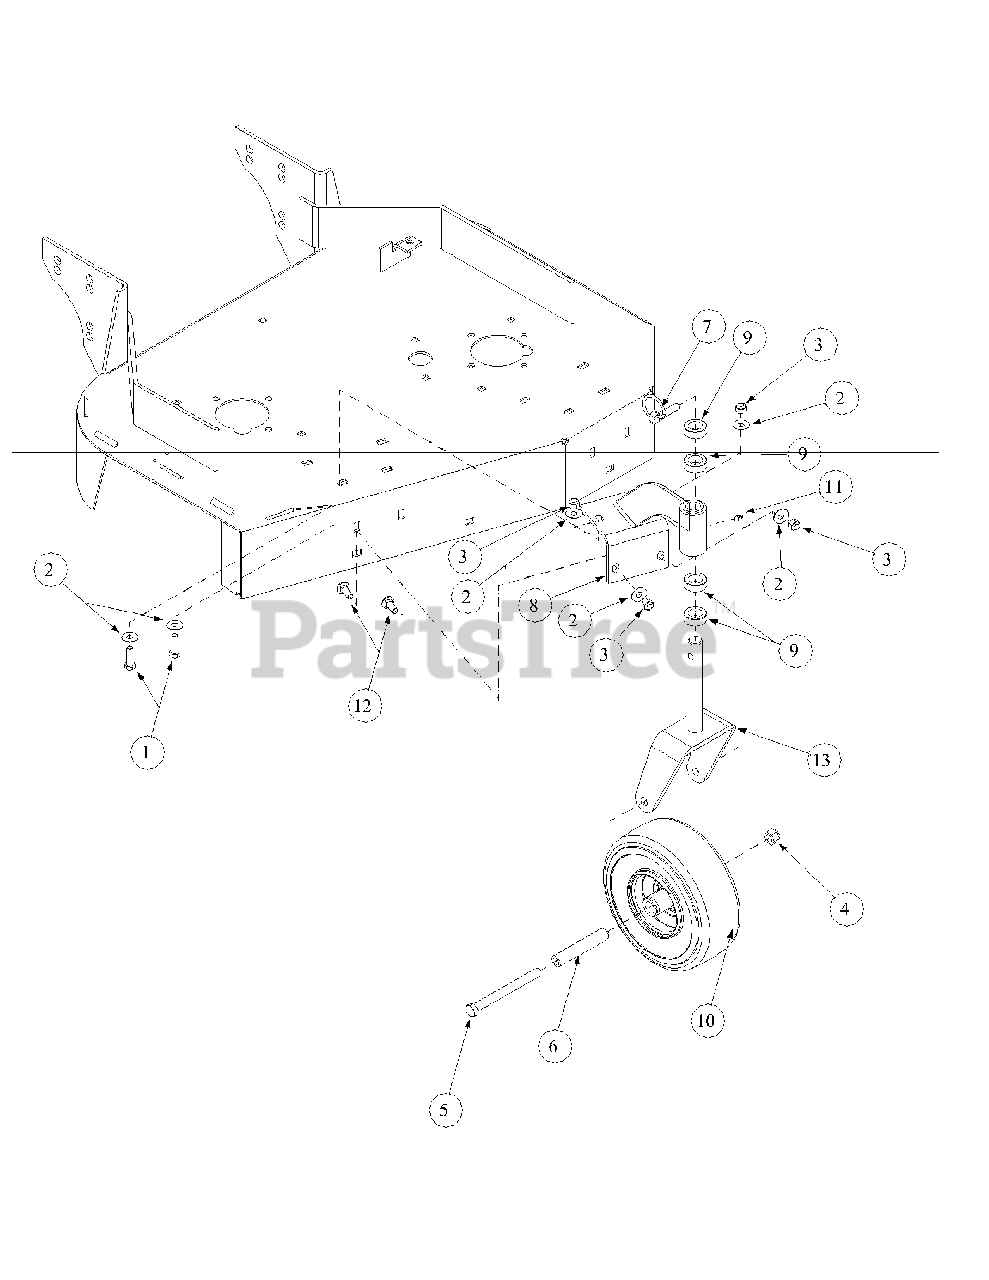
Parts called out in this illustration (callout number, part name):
1	Hex Cap Screw, 3/8-16 x 1-1/4
2	Flat Washer, 3/8 Zinc
3	Lock Nut, Nylon Insert, 3/8-16
4	Lock Nut, Nylon Insert, 1/2-13
5	Hex Cap Screw, 1/2-20, 5.50
6	Spacer Wheel
7	Klik Pin, 1.75
8	Caster Bracket Assembly
9	Spacer, Caster
10	Wheel Assembly, 9.0 x 3.50-4
11	Grease Fitting, 1/4-28 x 3/16
12	Carriage Bolt, 3/8-16 x 1
13	Caster Yoke Assembly, Weldment
